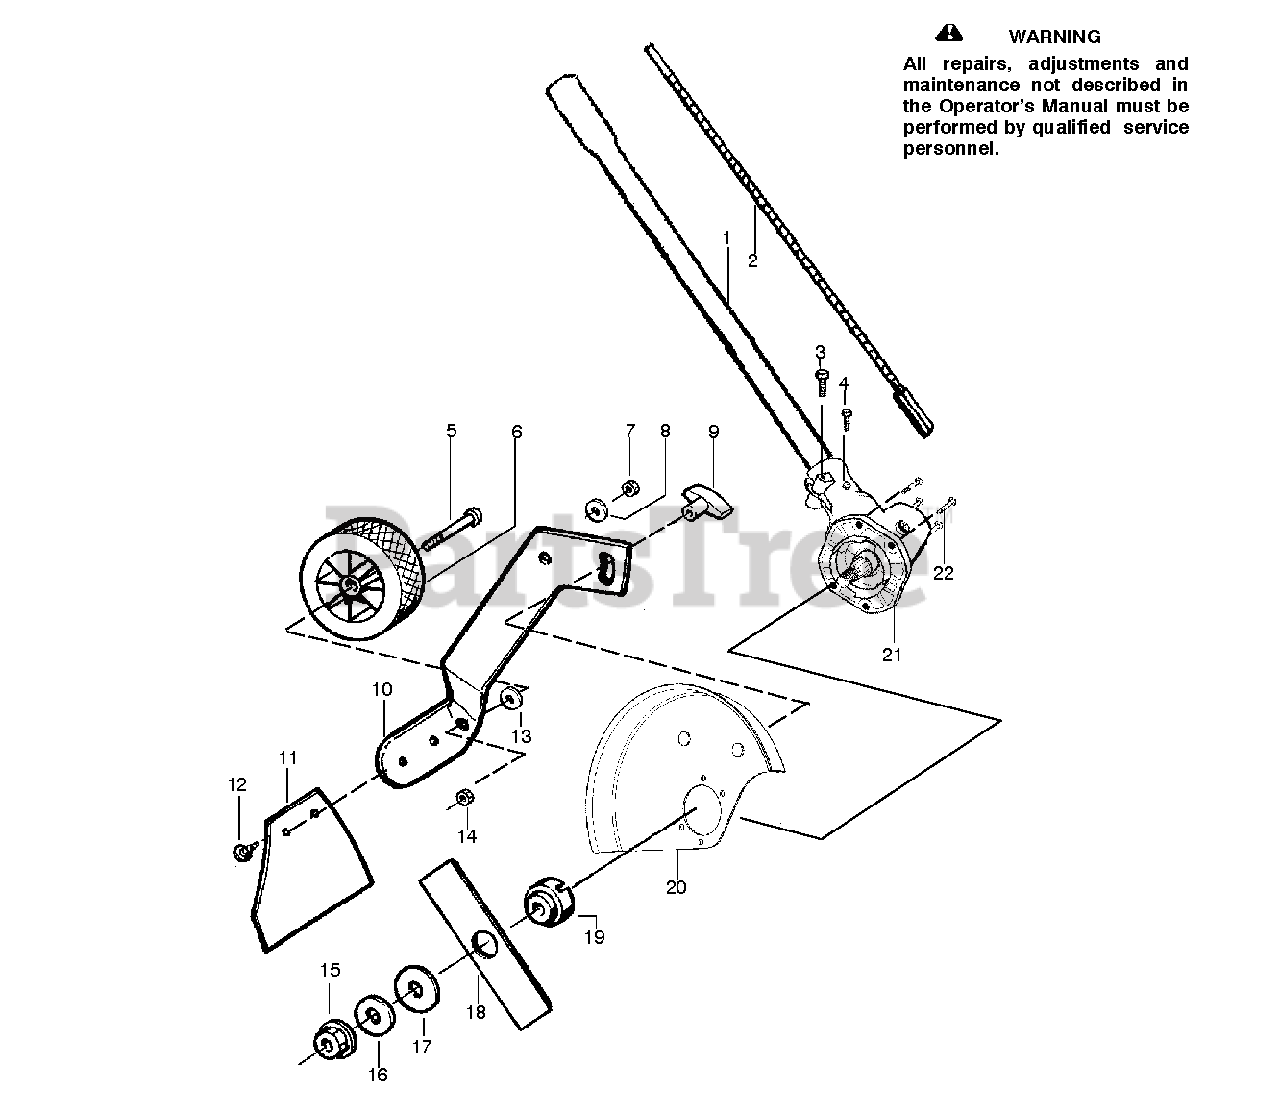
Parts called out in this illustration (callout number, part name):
1	DRIVE SHAFT KIT EDGER
2	FLEXSHAFT
3	SCREW - CARB. ADAPTOR
4	SCREW 8-16 X 9/16 (PLAS
5	BOLT-SHOULDER AXLE
6	WHEEL-4"(FRONT)(RUBBER)
10	WHEEL BRKT ADJ
11	KIT MUD FLAP
12	FASTENER MUD FLAP
15	NUT-FLANGE (LH)
16	WASHER BELLVILLE
17	WASHER-FLAT.
18	7.5" BLADE
19	DUST CUP
20	KIT,EDGER GUARD
21	GEARBOX
22	SCR 10-24 MS LDK PAN PH
